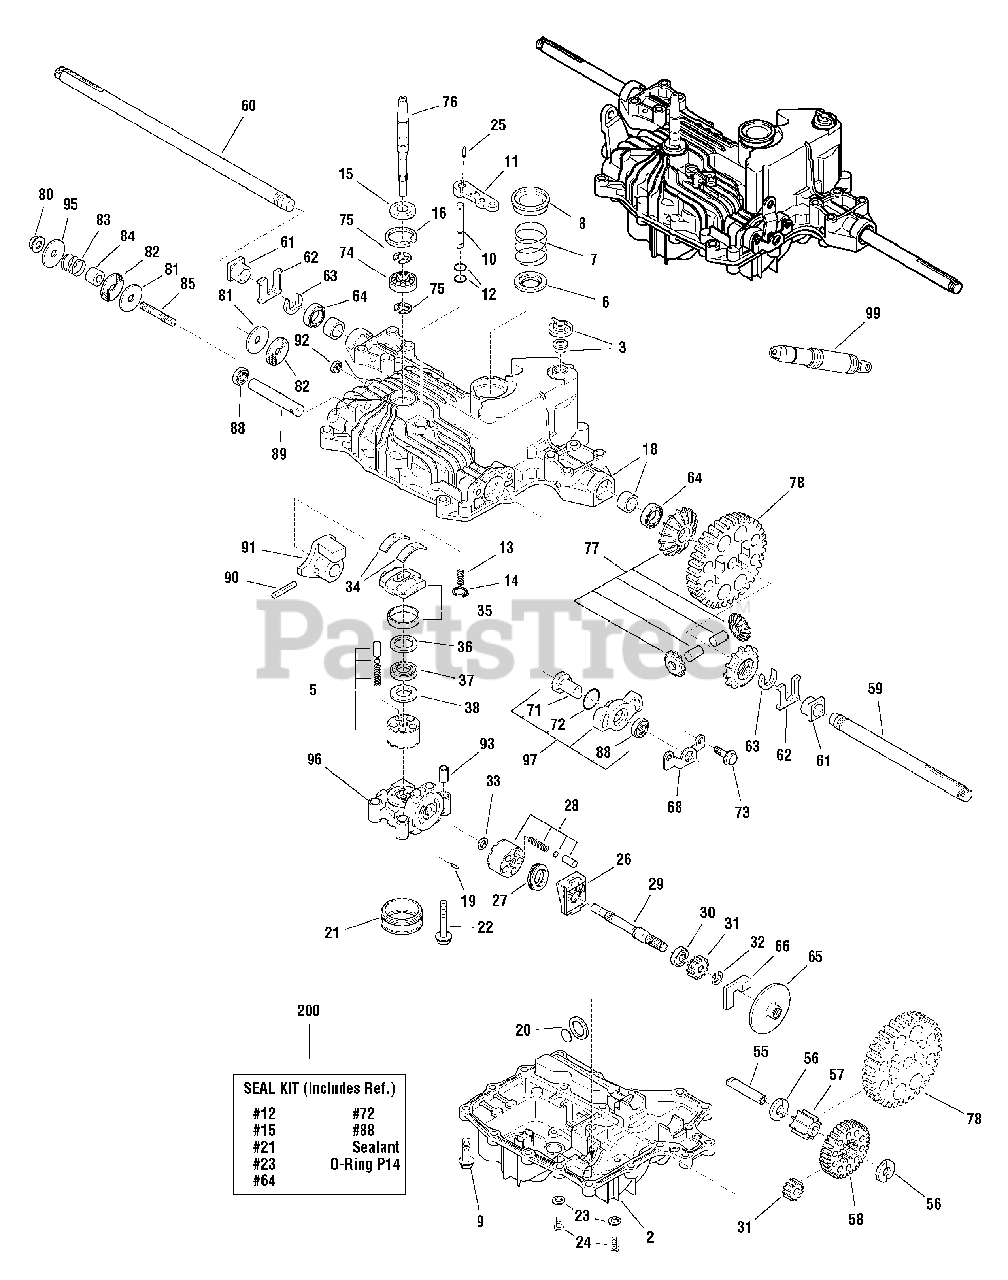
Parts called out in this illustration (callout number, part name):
2	LOWER HOUSING
5	CYLINDER BLOCK CMP.
7	SPRING, Filter
8	SEALING CAP
9	TAPPING SCREW
10	SHAFT , Bypass
11	LEVER , Bypass
12	O-RING, 1A P10A
15	SEAL, TC
18	UPPER HOUSING CMP.
21	FILTER
23	WASHER, Seal 8
24	BOLT 8 x 12
28	CYLINDER BLOCK CMP.
29	MOTOR SHAFT
30	BEARING
34	THRUST METAL
35	SWASH PLATE CMP.
36	THRUST PLATE B
38	THRUST PLATE A
55	REDUCTION SHAFT
57	FINAL PINION
58	REDUCTION GEAR
59	AXLE SHAFT, LH
60	AXLE SHAFT, RH
62	THRUST WASHER
64	SEAL
65	DISK, Brake
66	SHOE, Brake
68	PLATE, Brake
71	SHAFT, Brake
75	RING
77	DIFF. GEAR KIT
81	FRICTION PLATE CMP.
83	SPRING, Friction
89	CONTROL SHAFT
91	CONTROL ARM ASSEMBLY
92	CAP, Sealing
96	CENTER CASE B CMP.
97	BRAKE CAM KIT (Includes Ref. Nos. 71, 72, & 88)
99	SHOCK ABSORBER
200	K51/K56 SEAL KIT (Includes Ref. Nos. 12, 15, 21, 23, 64, 72, & 88)
